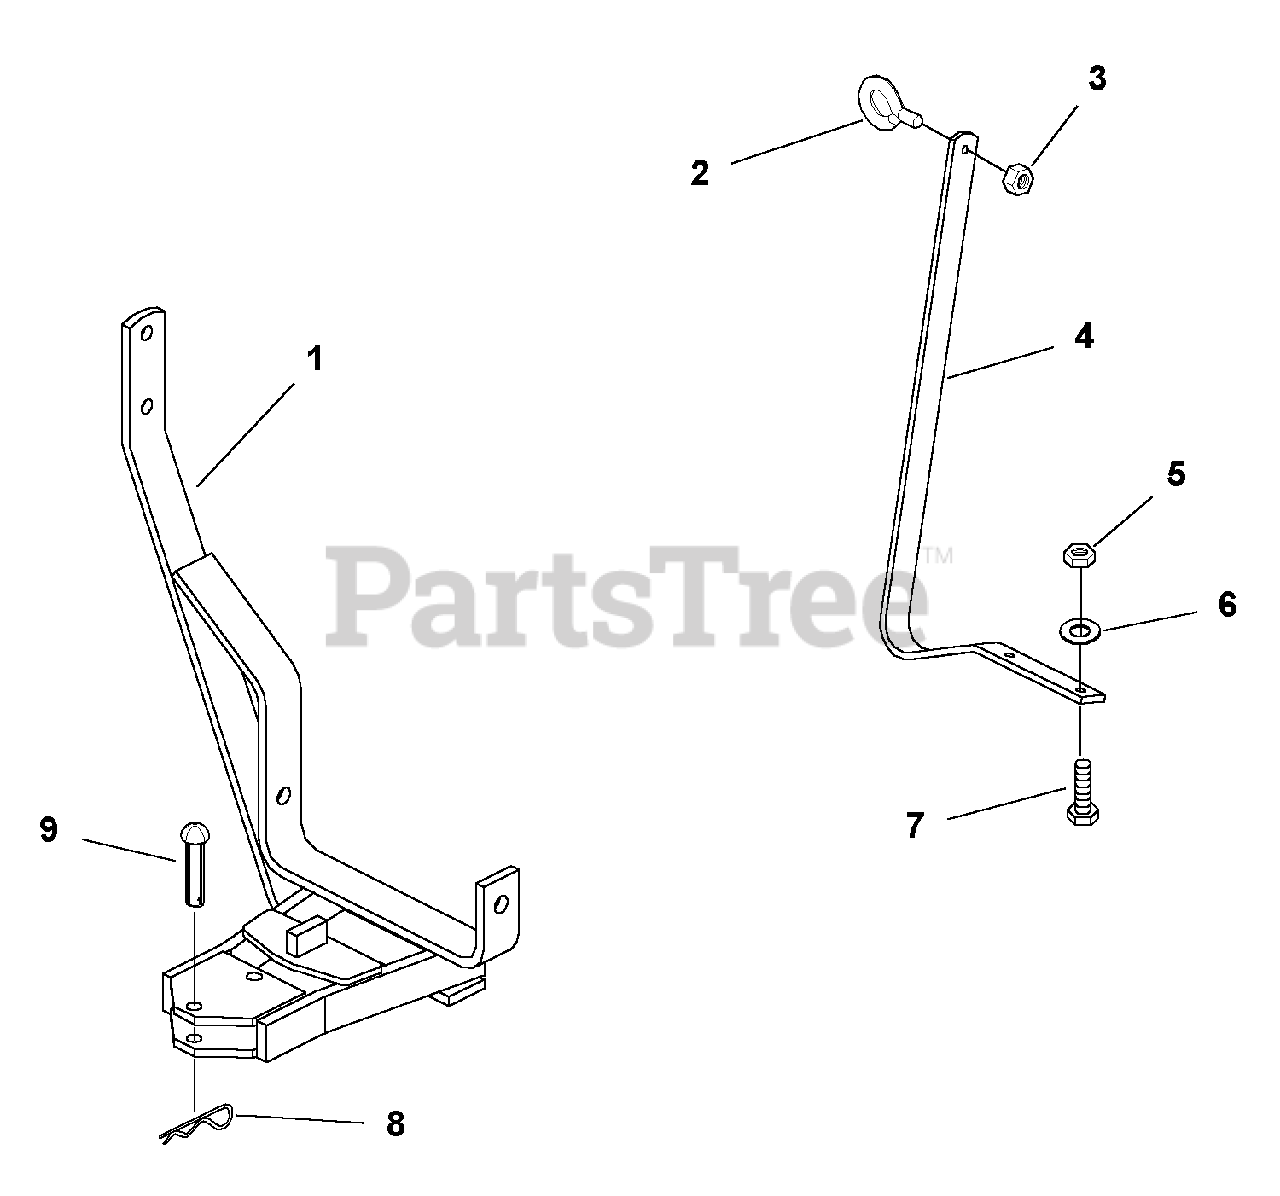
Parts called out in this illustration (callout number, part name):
1	PUSH BAR ASSEMBLY
3	NUT, Hex, 1/4-20
4	Support, Control Rod
5	NUT, Hex, 5/16-18
6	LOCKWASHER, 5/16
7	CAPSCREW, Hex Head, 5/16-18 x 1
8	CLIP, Hair Pin
9	PIN, Pivot
